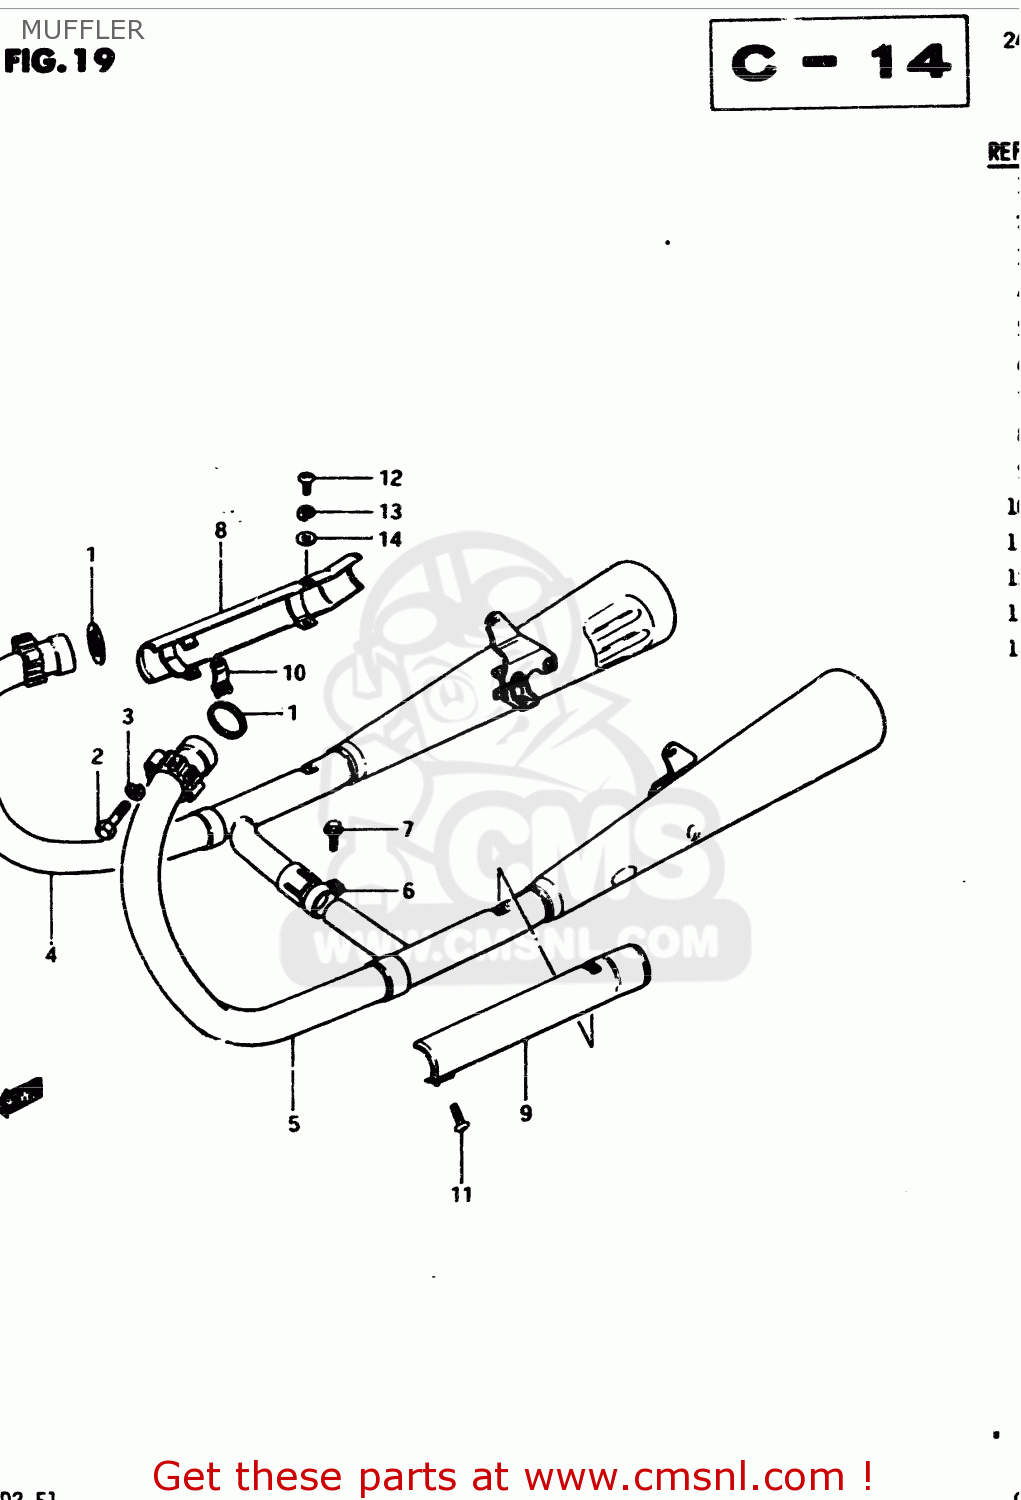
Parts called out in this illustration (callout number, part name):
1	GASKET,EXHAUST PIPE (NAS)
2	BOLT 8X40
3	LOCK WASHER
4	MUFFLER ASSY,R
5	MUFFLER ASSY,L
6	CLAMP
7	BOLT
8	COVER, MUFFLER RH
9	COVER, MUFFLER LH
10	CLAMP,MUFFLER COVER
11	SCREW
12	SCREW
13	LOCK WASHER
14	WASHER
